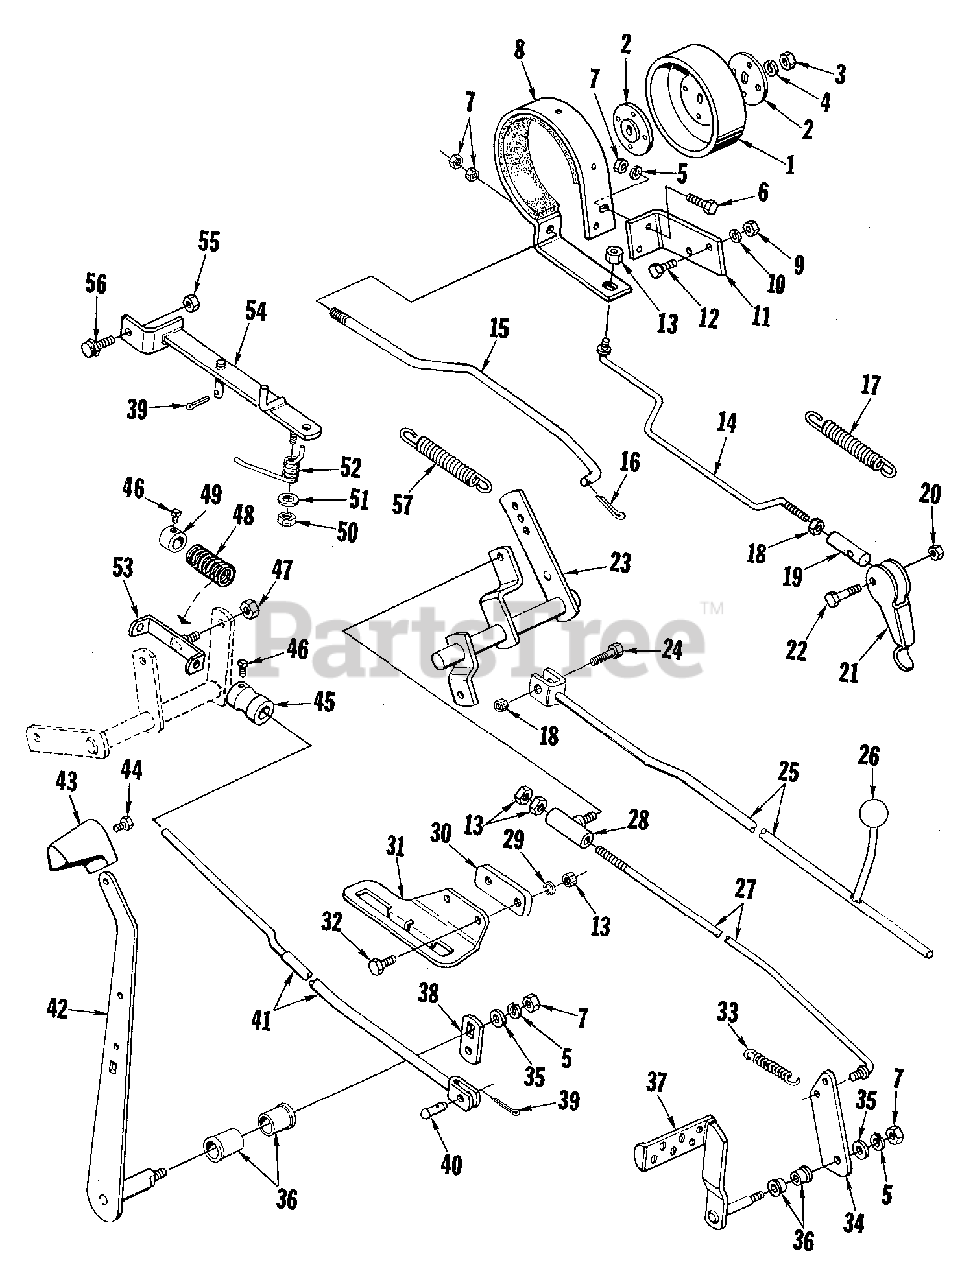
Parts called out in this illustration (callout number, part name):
2	WASHER, Special
3	NUT, Hex, Full, 7/16-14
4	WASHER, Lock, 7/16
5	WASHER, Lock, 3/8
6	SCREW, Hex Cap, 3/8-16 x 1
7	NUT, Hex Full, 3/8-16
8	BRAKE BAND ASSEMBLY
9	NUT, Hex Full, 1/4-20
10	WASHER, Lock, 1/4
11	BRACKET, Brake Band
12	SCREW, Hex Cap, 1/4-20 x 3/4
13	NUT, Hex Full, 5/16-18
14	ROD, Parking Brake
18	NUT, Hex Full, 5/16-18
20	NUT, Hex Lock Full, 1/4-20
21	LEVER, Parking Brake
22	SCREW, Hex Cap, 1/4-20 x 1-1/4
23	LEVER, Pivot
24	SCREW, Hex Cap, 5/16-18 x 1-1/2
27	ROD ASSEMBLY, Clutch & Brake
28	GUIDE, Rod Assembly
29	WASHER, Lock, 5/16
30	SPACER, Speed Control Quadrant
32	SCREW, Hex Head, 5/16-18 x 3/4
33	SPRING, Tension
34	ARM, Foot Pedal
35	WASHER, Plain, 3/8
36	BUSHING, Flanged
37	FOOT PEDAL ASSEMBLY
39	PIN, Cotter, 3/32 x 3/4
41	ROD ASSEMBLY SPEED CONTROL
42	LEVER ASSEMBLY SPEED CONTROL
44	SCREW, Hex Self Forming
45	DETENT, Brake
46	SCREW, Set Square Head, 1/4-20 x 3/8
47	NUT, Hex Full Lock, 3/8-16
50	NUT, Hex Jam, 3/8-16
51	WASHER, 5/16
53	ROD, Guide Assembly
54	BRAKE, Lever Assembly
55	NUT, Hex Jam, 5/16-18
